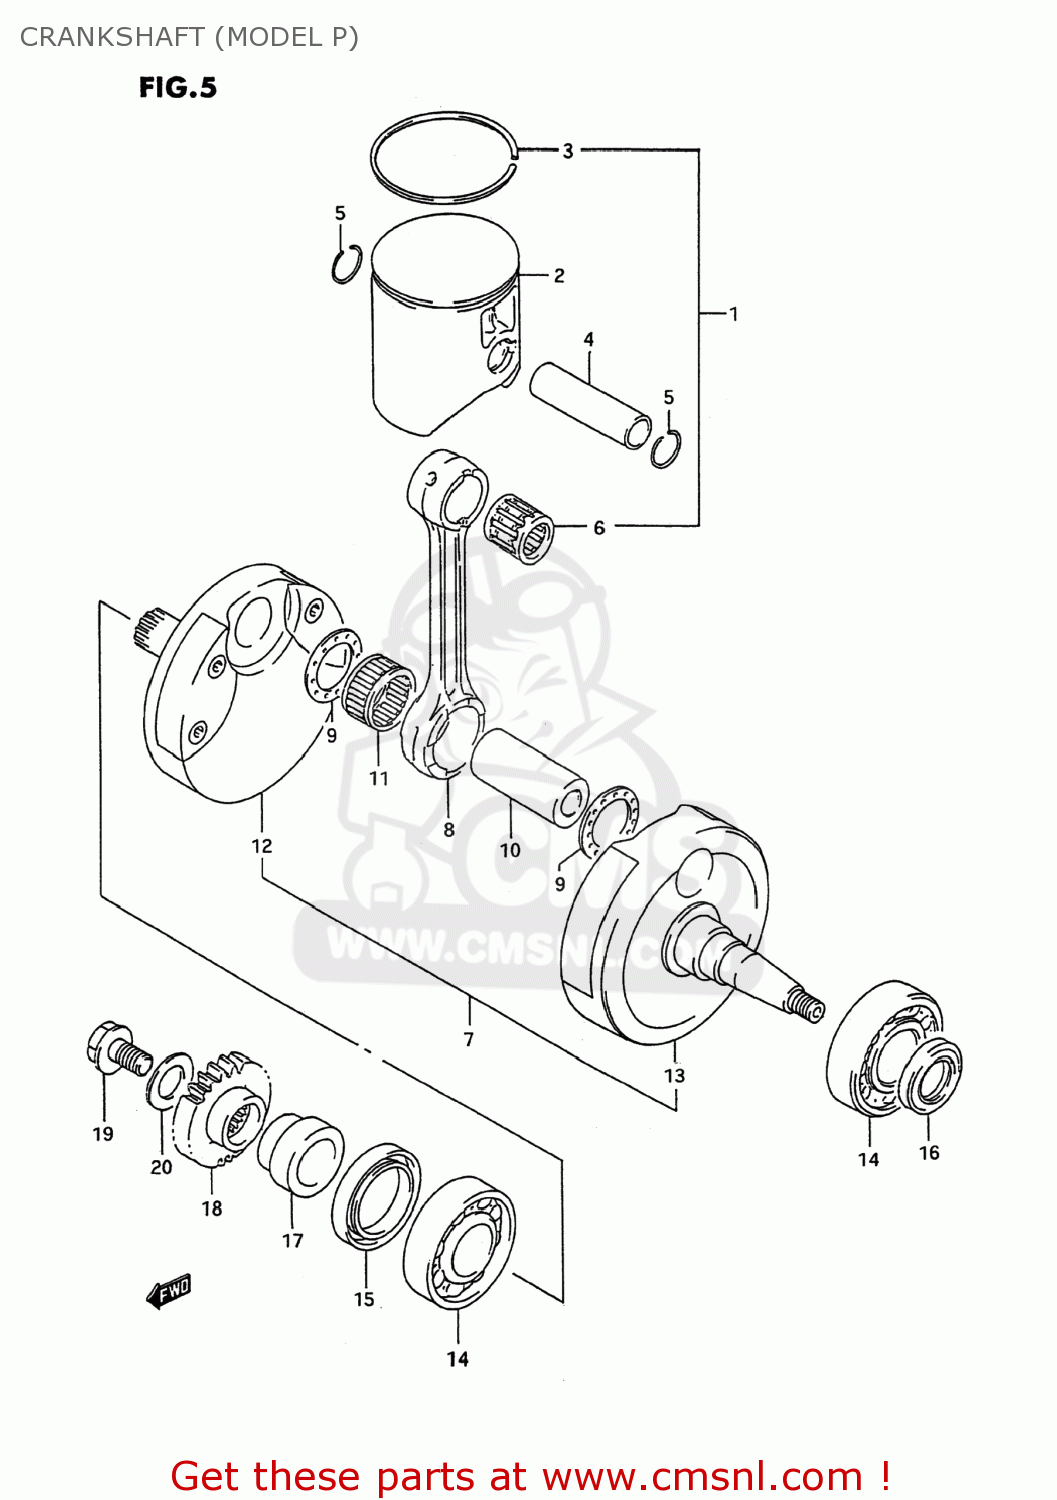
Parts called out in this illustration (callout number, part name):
2	PISTON
3	RING,PISTON
4	PIN,PISTON
5	CIRCLIP
6	BEARING(18X23X22)
7	CRANKSHAFT ASSY
8	ROD,CONNECTING
9	WASHER(24X38.5X1.5)
10	PIN,CRANK
11	BEARING(24X30X20)
12	CRANKSHAFT,R
13	CRANKSHAFT,L
14	BEARING(25X62X17)
15	SEAL,OIL(36X52X7)
16	SEAL,OIL(20X37X6)
17	SPACER,PRIMARY DRIVE GEAR
18	GEAR,PRIMARY DRIVE (NT:
19	BOLT,PRIMARY DRIVE GEAR
20	WASHER
21	TOP END KIT,ENGINE
